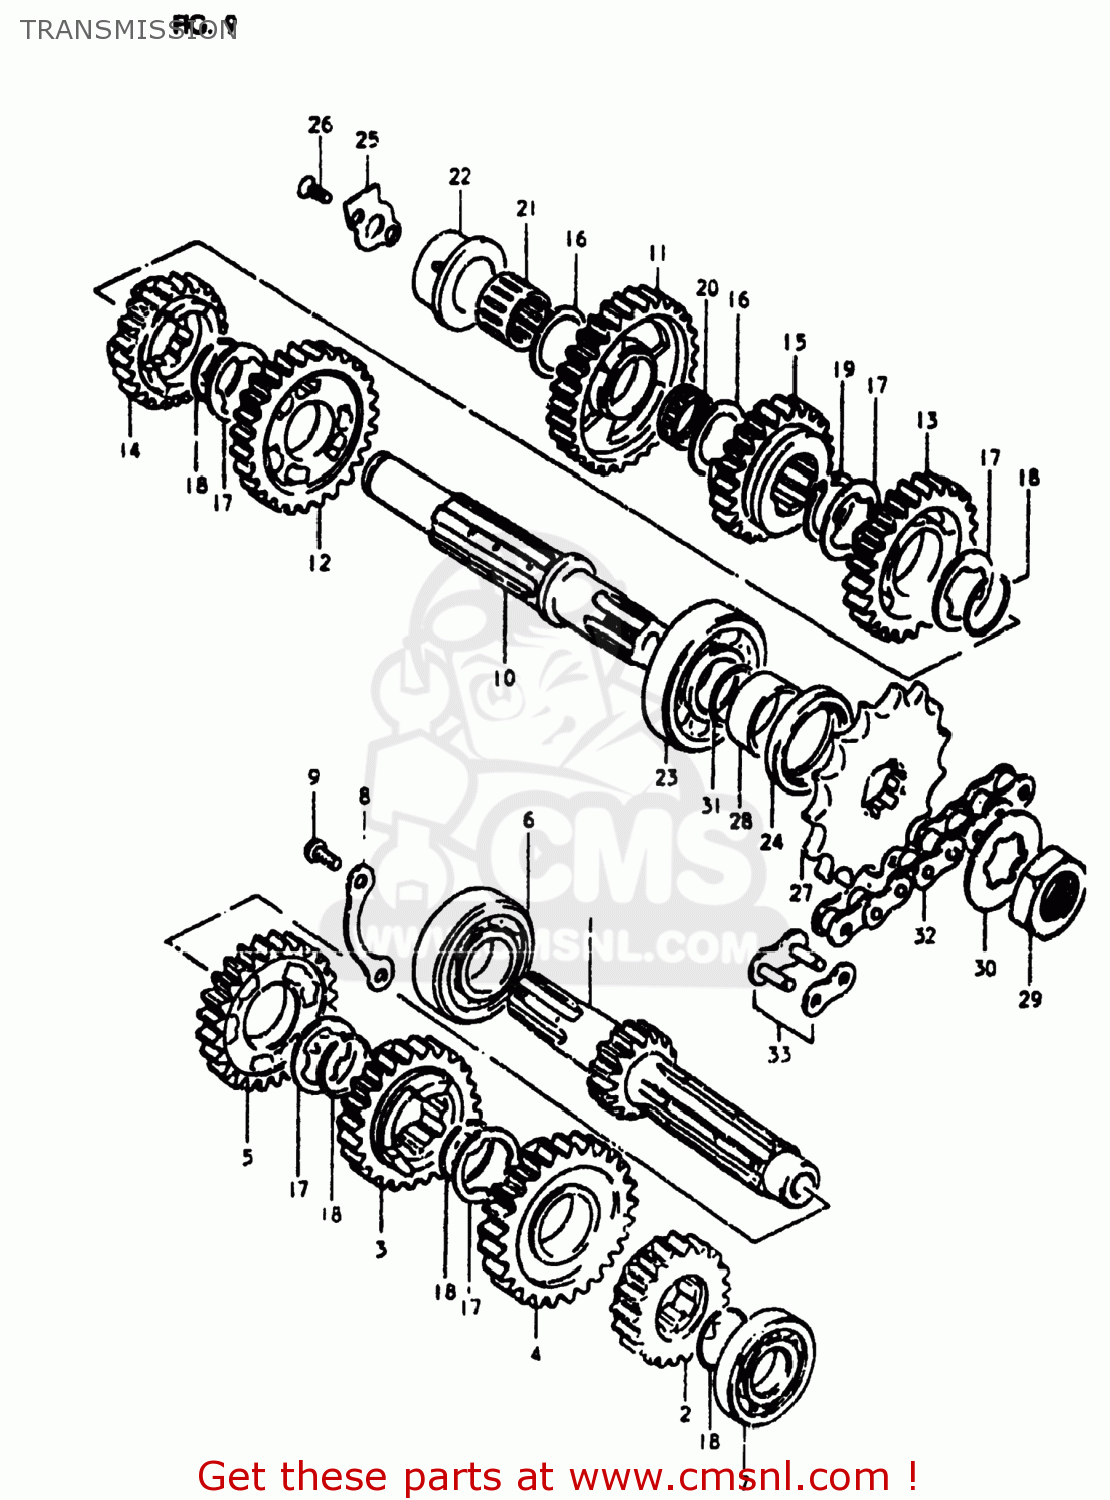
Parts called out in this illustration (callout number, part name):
1	SHAFT,COUNTER
2	GEAR,SECOND DRIVE
3	GEAR,THIRD DRIVE
4	GEAR,FOURTH DRIVE
5	GEAR,FIFTH DRIVE
6	BEARING
7	BEARING, LH
8	PLATE,COUNTERSHAFT BEARING
9	SCREW 6X12
10	SHAFT,DRIVE
11	GEAR,FIRST DRIVEN
12	GEAR,SECOND DRIVEN
13	GEAR,THIRD DRIVEN
14	GEAR,FOURTH DRIVEN
15	GEAR,FIFTH DRIVEN
16	WASHER (20X30X1)
17	WASHER,LOCK
18	RING,SNAP
19	CIRCLIP
20	BEARING(20X24X10).8
21	BEARING(20X24X16.8)
22	BUSHING
23	BEARING
24	SEAL,OIL(32X42X6)
25	PLATE,DRIVESHAFT BEARING
26	SCREW
27	SPROCKET,ENGINE
28	SPACER(22X32X11.5)
29	NUT
30	WASHER,LOCK
31	O RING(D:1.7,ID:22)
32	CHAIN ASSEMBLY,DRIVE
33	JOINT ASSEMBLY,CHAIN
